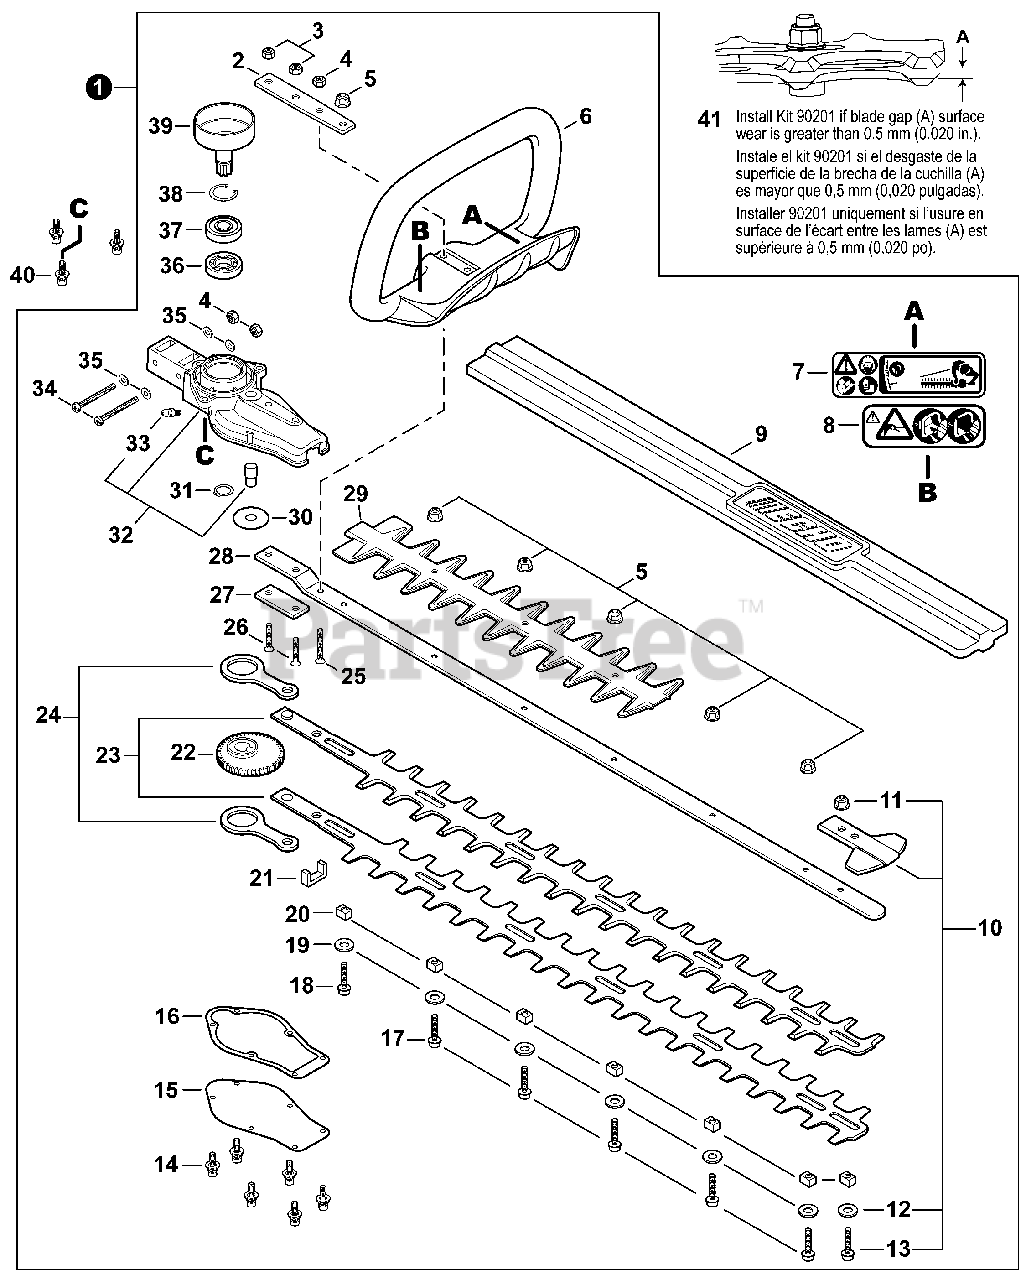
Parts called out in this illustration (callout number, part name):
1	CUTTING HEAD KIT
2	PLATE, SUPPORT
3	NUT, HEX M6
4	NUT, LOCK M5
5	NUT, FLANGE M5
6	HANDLE, FRONT
7	LABEL, CAUTION - ISO
8	LABEL, CAUTION
9	SCABBARD 26.5"
10	TIP GUARD KIT
11	NUT, FLANGE M5
12	WASHER 5
13	BOLT 5×20
14	BOLT 4×10
15	COVER, GEAR CASE
16	GASKET, GEAR CASE
17	BOLT 5×20
18	BOLT 5×40
19	WASHER 5
20	GUIDE, BLADE 5
23	CUTTER 24"
24	ROD, CONNECTING
25	SCREW 5×30
26	SCREW 6×25
27	PLATE, EYE
28	SUPPORT, BLADE 24"
29	GUARD, CUTTER BLADE
31	RING, SNAP 14
32	GEAR CASE ASSY
33	FITTING, GREASE
34	SCREW 5×45
35	WASHER, FLAT 5.5×10×0.8
36	BEARING, BALL 6202
37	BEARING, BALL 6202
38	RING, SNAP 35
39	DRUM, CLUTCH
40	BOLT 5×20
41	BLADE KIT, ADJUSTABLE
